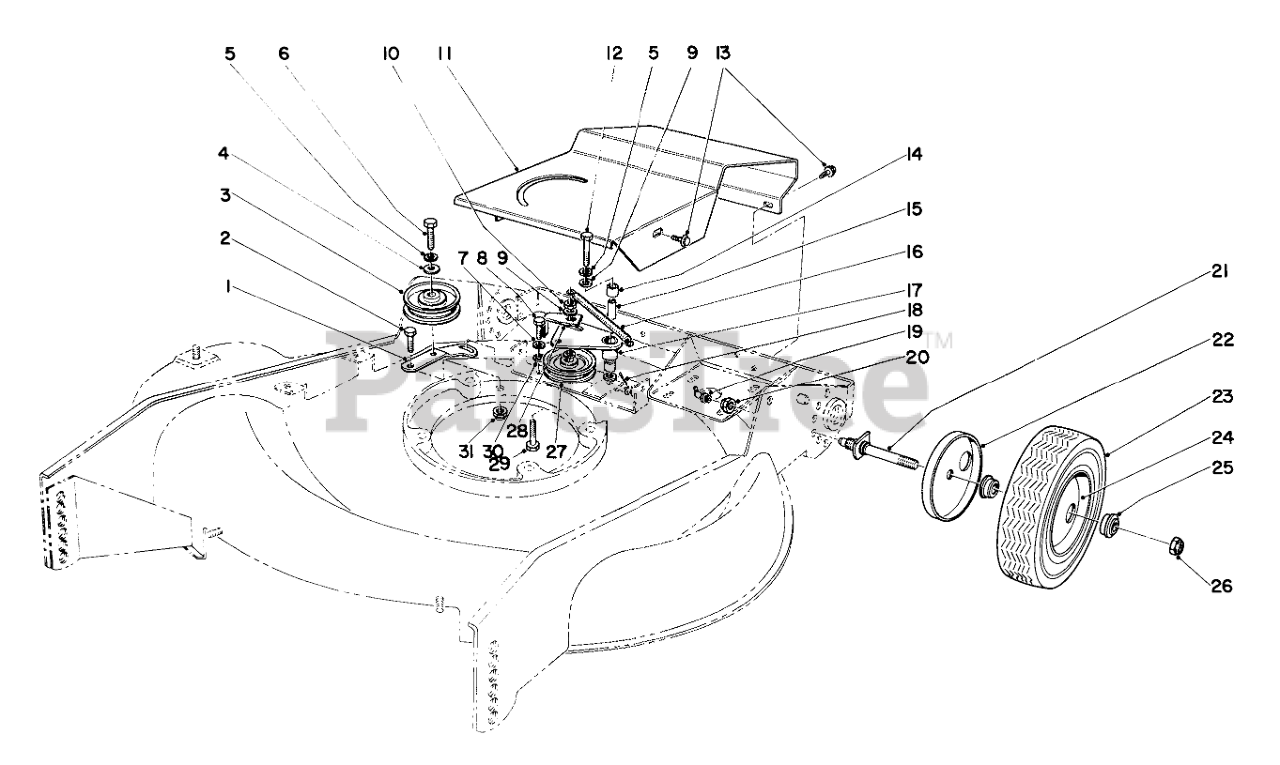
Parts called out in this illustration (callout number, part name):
1	Arm, Auxiliary Idler
2	SCREW-HH
3	PULLEY-IDLER
4	WASHER-FLAT
5	WASHER-LOCK
6	SCREW-HH
7	WASHER-LOCK, INTERNAL
8	SCREW-HH
9	WASHER-FLAT
10	Nut
11	Shroud
12	SCREW-HH
13	Screw
14	BUSHING
15	ROLLED SPACER
16	IDLER SPRING
17	Idler Arm (Incl. Ref. #14)
18	PIN-COTTER
19	GREASE FITTING
20	NUT-LOCK, NI
21	Spindle Assy. (Incl. Ref. #19)
22	WHEEL COVER
24	Drive Wheel Assy. w/Tire (Incl. Ref. #23 & 25)
25	BEARING-BALL
26	Nut
27	IDLER PULLEY R
29	Screw
30	WASHER-PLAIN
31	Nut
